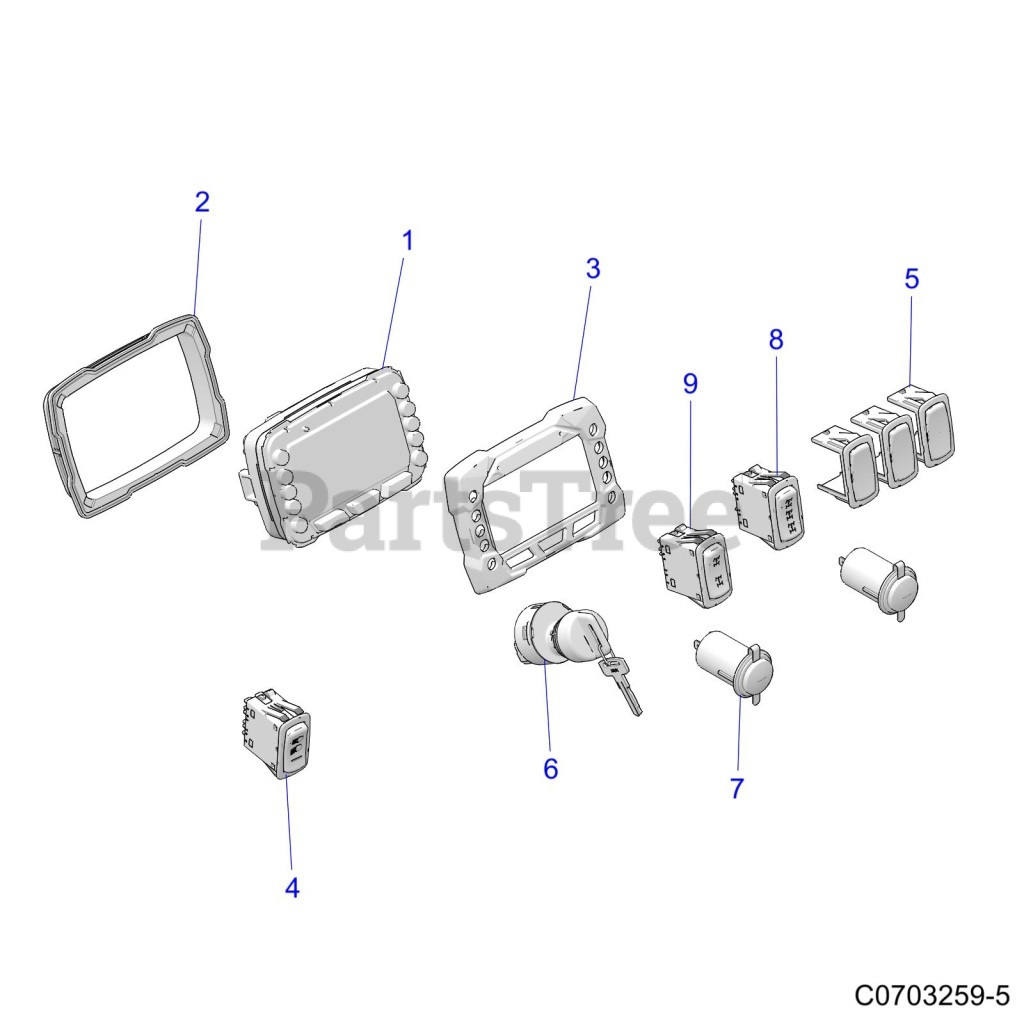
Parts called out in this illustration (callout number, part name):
1	ASM-CLUSTER,B1
2	GASKET-DIGITAL GAUGE
3	BEZEL-GAUGE,B1,UNBRANDED
4	SWITCH-HEADLIGHT
5	SWITCH-PLUG,BLANK
6	SWITCH-KEY,COMMON,3POS,SEALED
7	RECEPTACLE-POD MNT,12 VOLT
8	SWITCH-AWD
9	SWITCH-LOCK,DIFF
